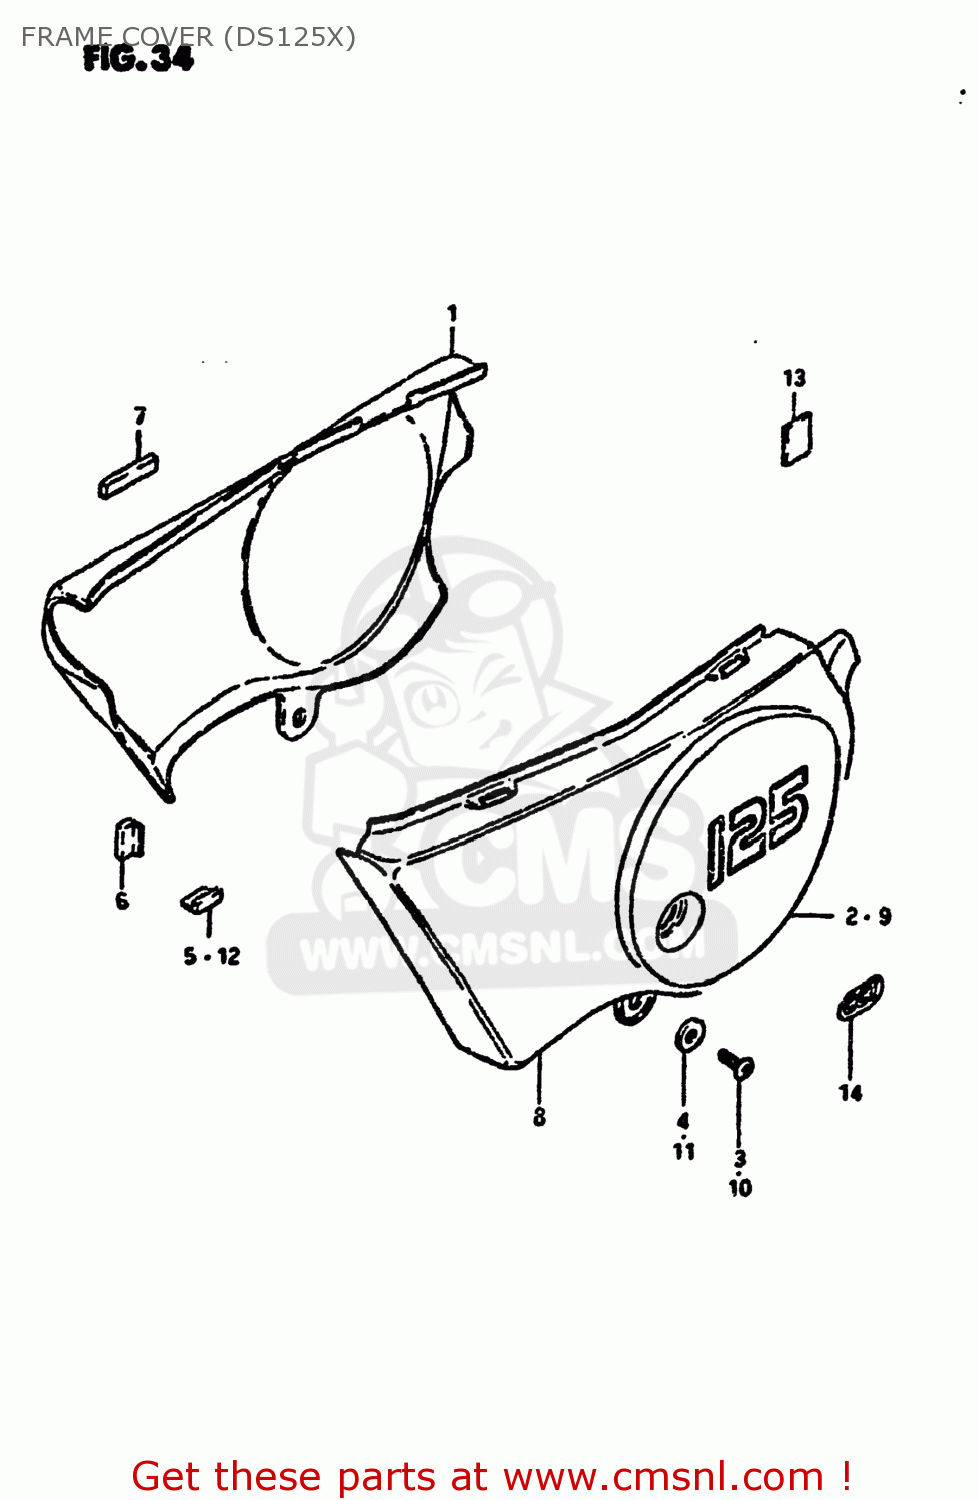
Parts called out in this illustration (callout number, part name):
1	COVER,FRAME,RIGHT
2	EMBLEM
3	SCREW 6X12
4	WASHER
5	CUSHION,FRAME COVER
6	CUSHION,FRAME COVER
7	CUSHION,FRAME COVER
8	COVER,FRAME,LEFT
9	EMBLEM,FRAME COVER
10	SCREW 6X12
11	WASHER
12	CUSHION,FRAME COVER
13	PROTECTOR(170X95X3.0)
14	EMBLEM,CCIS
